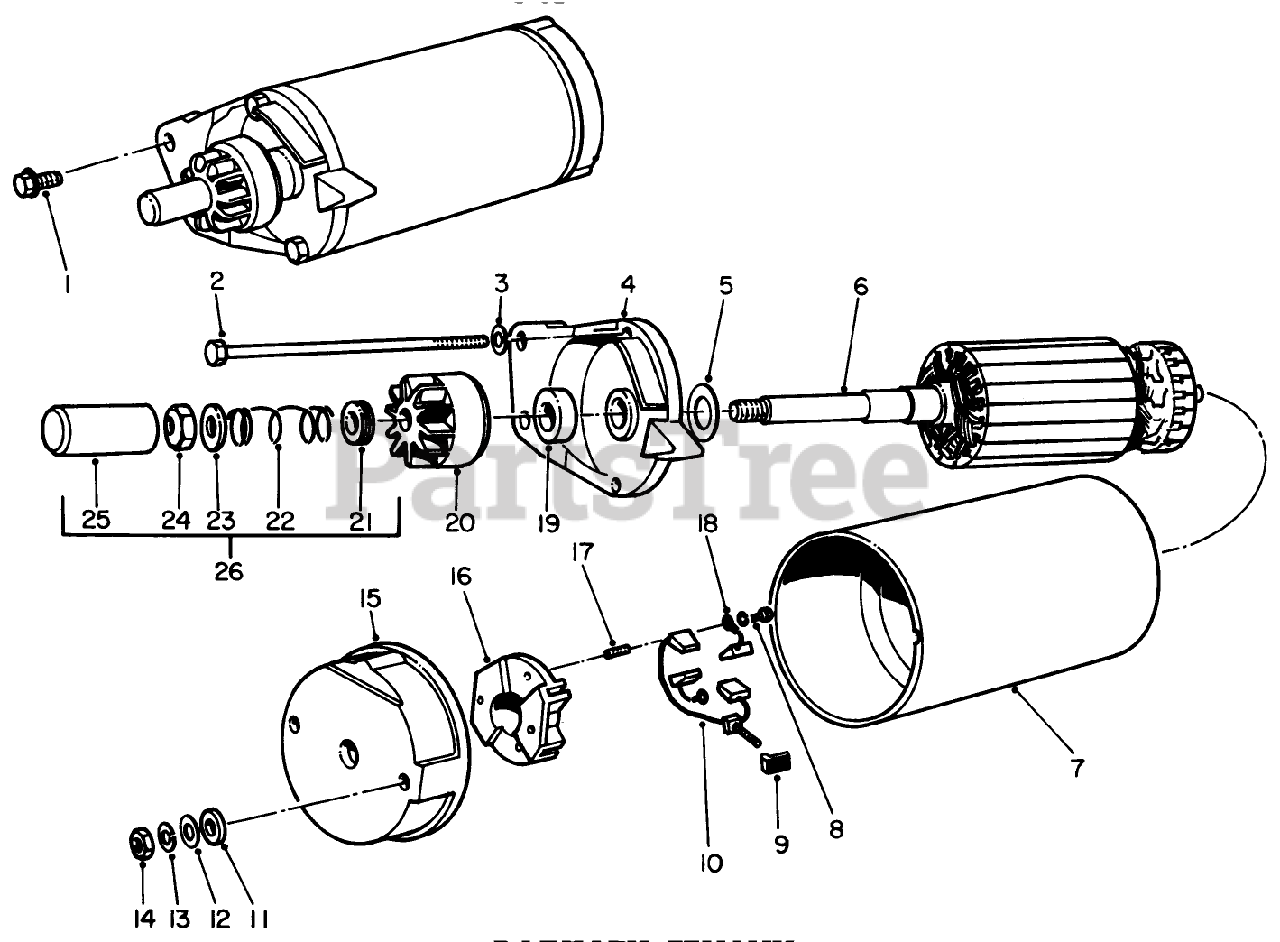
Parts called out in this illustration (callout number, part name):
1	Screw-Cap, Hex Hd.
2	Screw-Hex Hd.
3	Washer, Lock
4	Cap Assembly, Drive End
5	Washer, Armature Thrust
6	Armature
7	Housing, Starter Motor
8	Screw and Lockwasher
9	Bushing Insulation-Input Stud
10	Stud and Brush Assembly Input
11	Nut, Securing-Input Stud
12	Washer, Lock-Input Stud
13	Washer, Flat-Input Stud
14	Washer, Insulation-Input Stud
15	Cap Assembly, Commutator (Incl. Ref. #9-1416-1820)
16	Brush Holder
17	Spring, Brush
18	Brush, Ground
19	Cap, Dust
20	Drive Assembly
21	Spacer, Dust Cover
22	Spring, Anti-Drift
23	Washer, Stop Nut
24	Nut, Stop
25	Cover, Dust
26	Dust Cover Assembly (Incl. Ref. #22-26)
